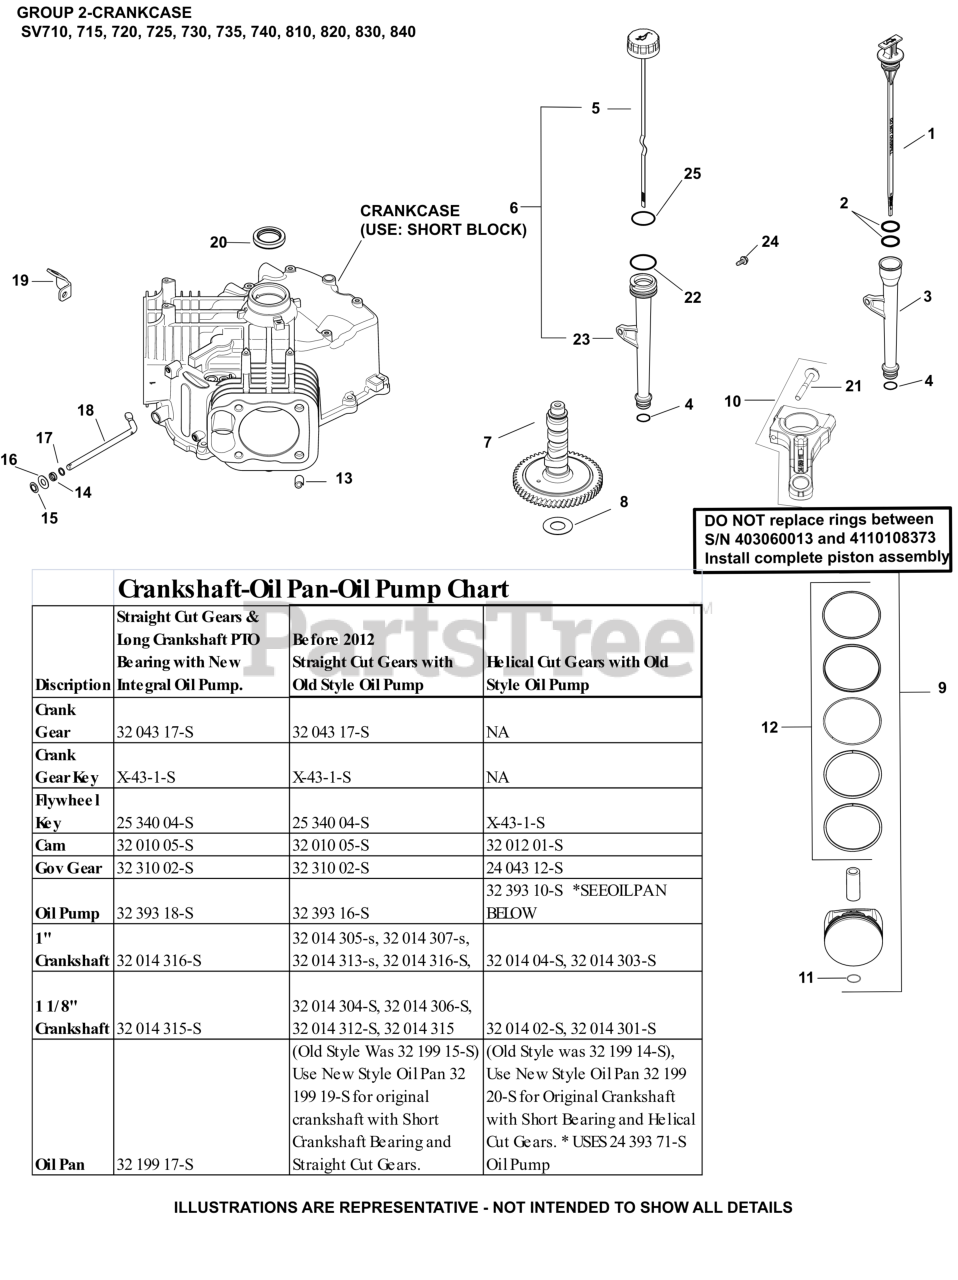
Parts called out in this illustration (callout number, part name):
1	DIPSTICK ASSEMBLY
3	TUBE ASSEMBLY-(#DSC)
4	O-RING, LOWER OIL FILL TUBE
5	RETAINER, BREATHER REED
6	REED, BREATHER
7	CAM ASSEMBLY
9	KIT, PISTON 725CC (STD) STYLE B
9	KIT, PISTON 725CC (.08) STYLE B
9	KIT, PISTON 725CC (.25) STYLE B
9	KIT, PISTON 725CC (.50) STYLE B
10	ROD, ASSY CON (STD)-USE 24 067 30-S
10	ROD, ASSY CON(.25mm) -USE 24 067 31-S
11	RETAINER, PISTON PIN
12	RING SET(STD)STYLE B-1.2mm Tp RING THICK
12	RING SET(.08)STYLE B-1.2mm RING THICK
12	RING SET(.25)STYLE B-1.2mm Tp RING THICK
12	RING SET(.50)STYLE B-1.2mm Tp RING THICK
13	PIN, LOCATING
14	SEAL, GOVERNOR CROSS SHAFT
15	RETAINER, RING
16	WASHER, FLAT 9 MM
17	WASHER, FLAT 11/32"
18	SHAFT, GOVERNOR CROSS-(#2414439S)
19	BRACKET, OIL FILL TUBE
20	SEAL, OIL (HELIX LIP)
21	KIT, ROD BOLTS-(#25086677S)
21	KIT, ROD BOLTS
24	SCREW, FLG THD FRM M5X0.8X13
